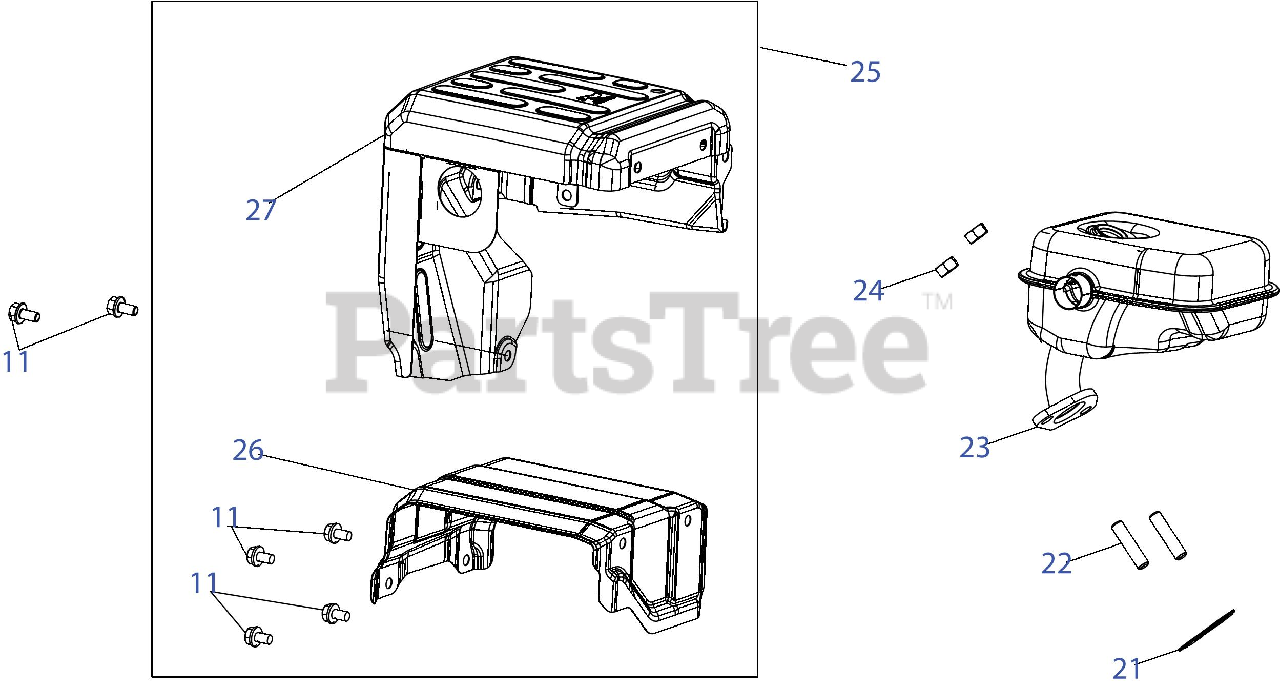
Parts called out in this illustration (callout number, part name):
11	Bolt, M6?12
21	Gasket, Muffler
22	Stud, M8?34
25	Muffler Guard
26	Muffler Inner Shield
27	Muffler Shield
